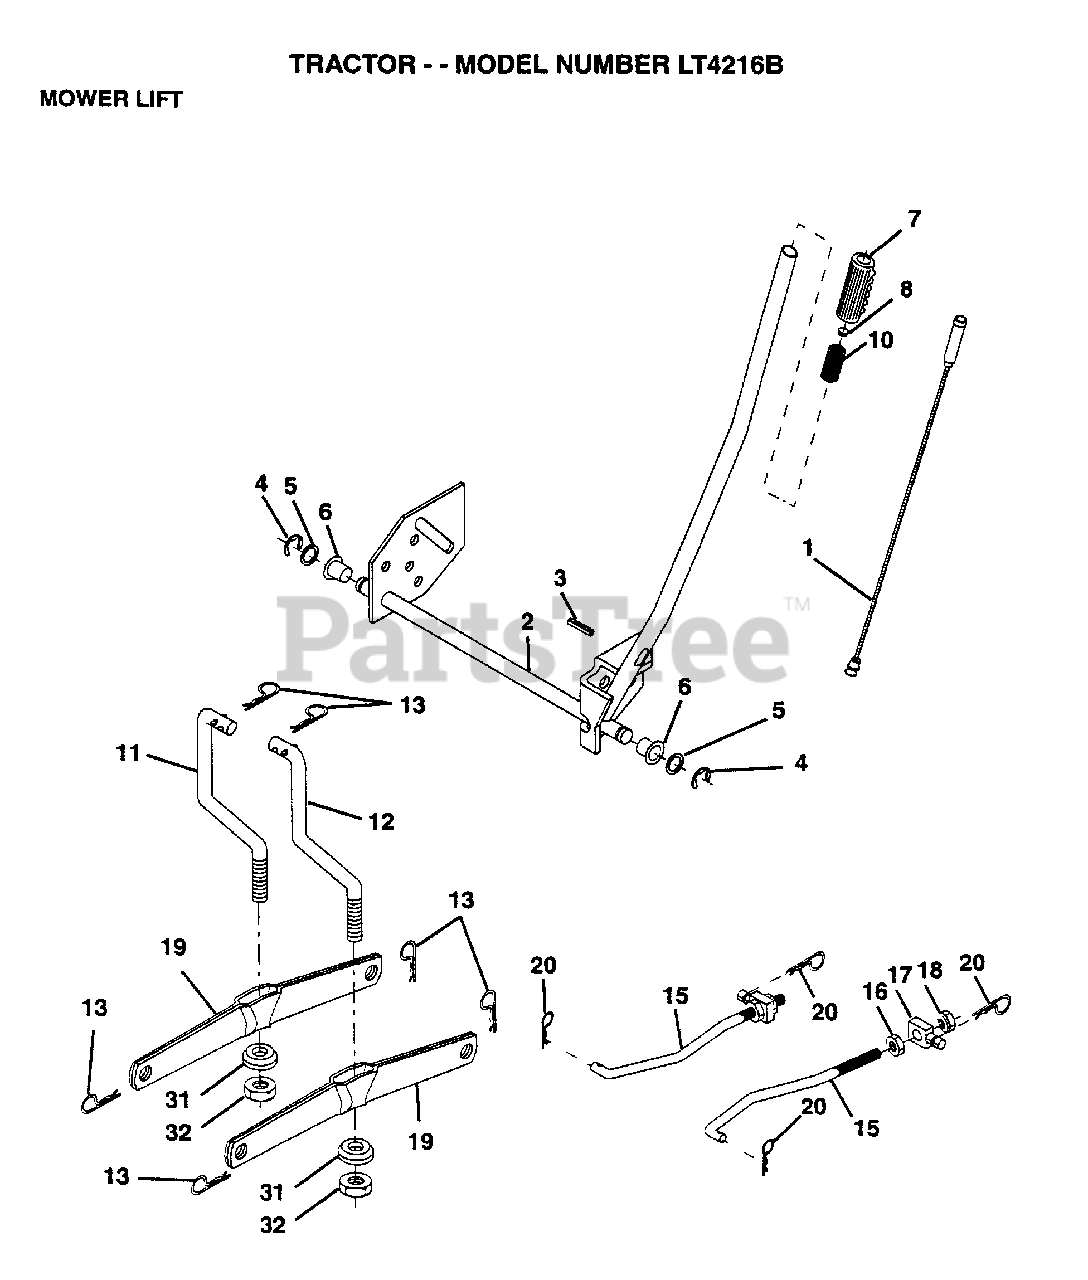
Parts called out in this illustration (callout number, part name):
1	WIRE ASM
3	PIN-GROOVE LT
5	WASHER
6	NYLON BEARING
7	GRIP
15	LINK.FRONT
16	NUT
17	TRUNION
18	NUT.LK.W/WSH.1/2.
19	ARM SUSP REAR
20	RETAINER.SPRING
31	BEARING PVT LH
32	NUT.LOCK.3/8-24
